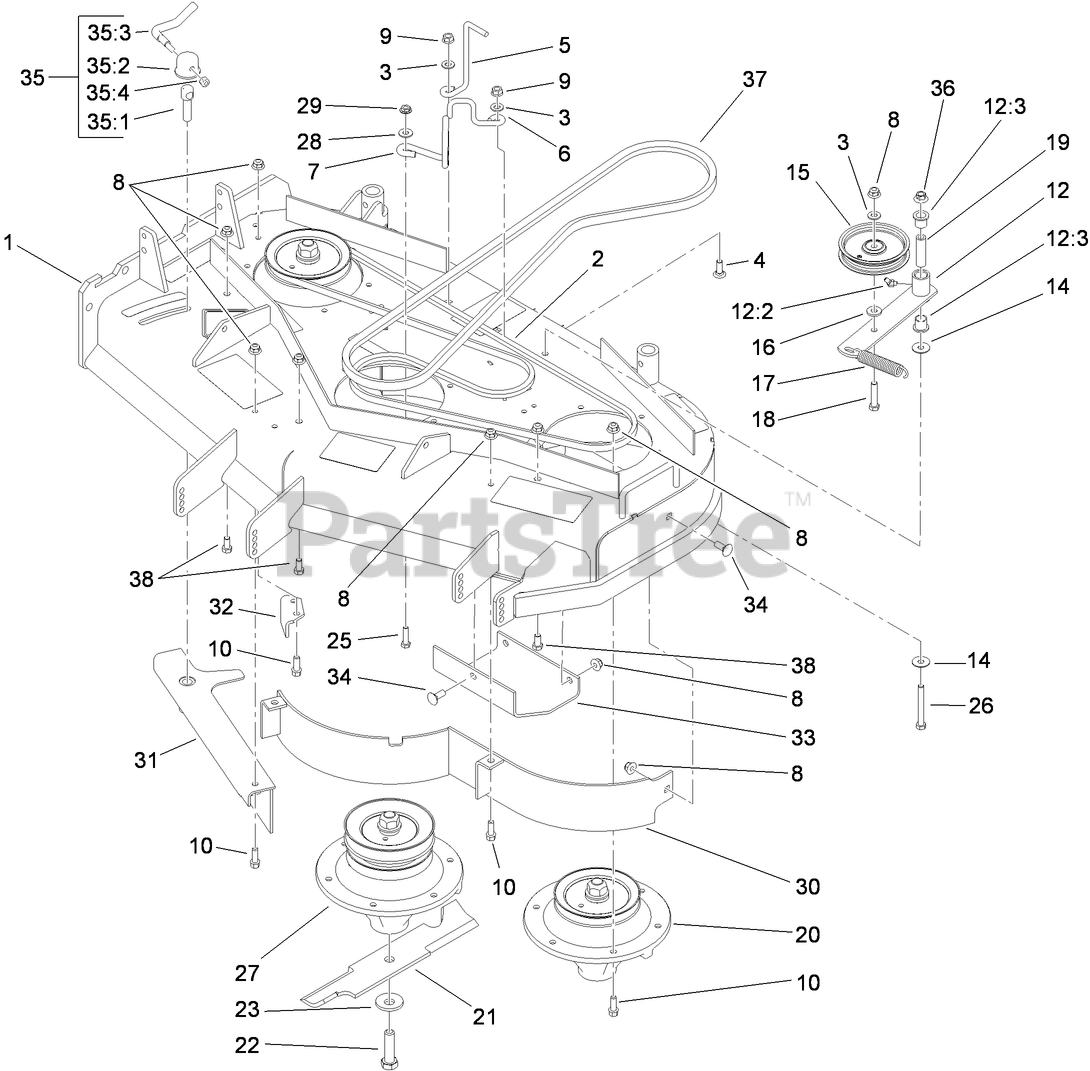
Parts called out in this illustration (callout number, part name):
1	DECK ASM
2	BELT-V
3	WASHER-FLAT
4	SCREW-CARR
5	GUIDE-BELT
6	GUIDE-BELT
7	GUIDE-BELT
8	NUT-HF, NI
9	NUT-HF
10	SCREW-HWH
12	IDLER ARM ASM
12:2	FITTING-LUBE, 45 DEG
12:3	BUSHING-FLANGE
14	WASHER
15	PULLEY-IDLER
16	WASHER-SPACER
17	SPRING-EXTENSION
18	SCREW-HH
19	SPACER
20	SPINDLE ASM
21	BLADE-14 INCH (HIGH SAIL)
22	SCREW-BLADE
23	Washer-Blade Bolt, Heavy
25	SCREW-HH
26	SCREW-HH
27	SPINDLE ASM
28	WASHER-FLAT
29	NUT-HF
30	BAFFLE ASM
31	ADJUST BAFFLE ASM
32	BAFFLE-DISCHARGE
33	PLATE-SKID
34	BOLT-CARR
35	LEVER ASM
35:1	Screw-Lock
35:2	CAP-LOCK
35:3	Lever-Lock
35:4	NUT-LOCK, NI
36	NUT-HF
37	BELT-V
38	SCREW-HH
